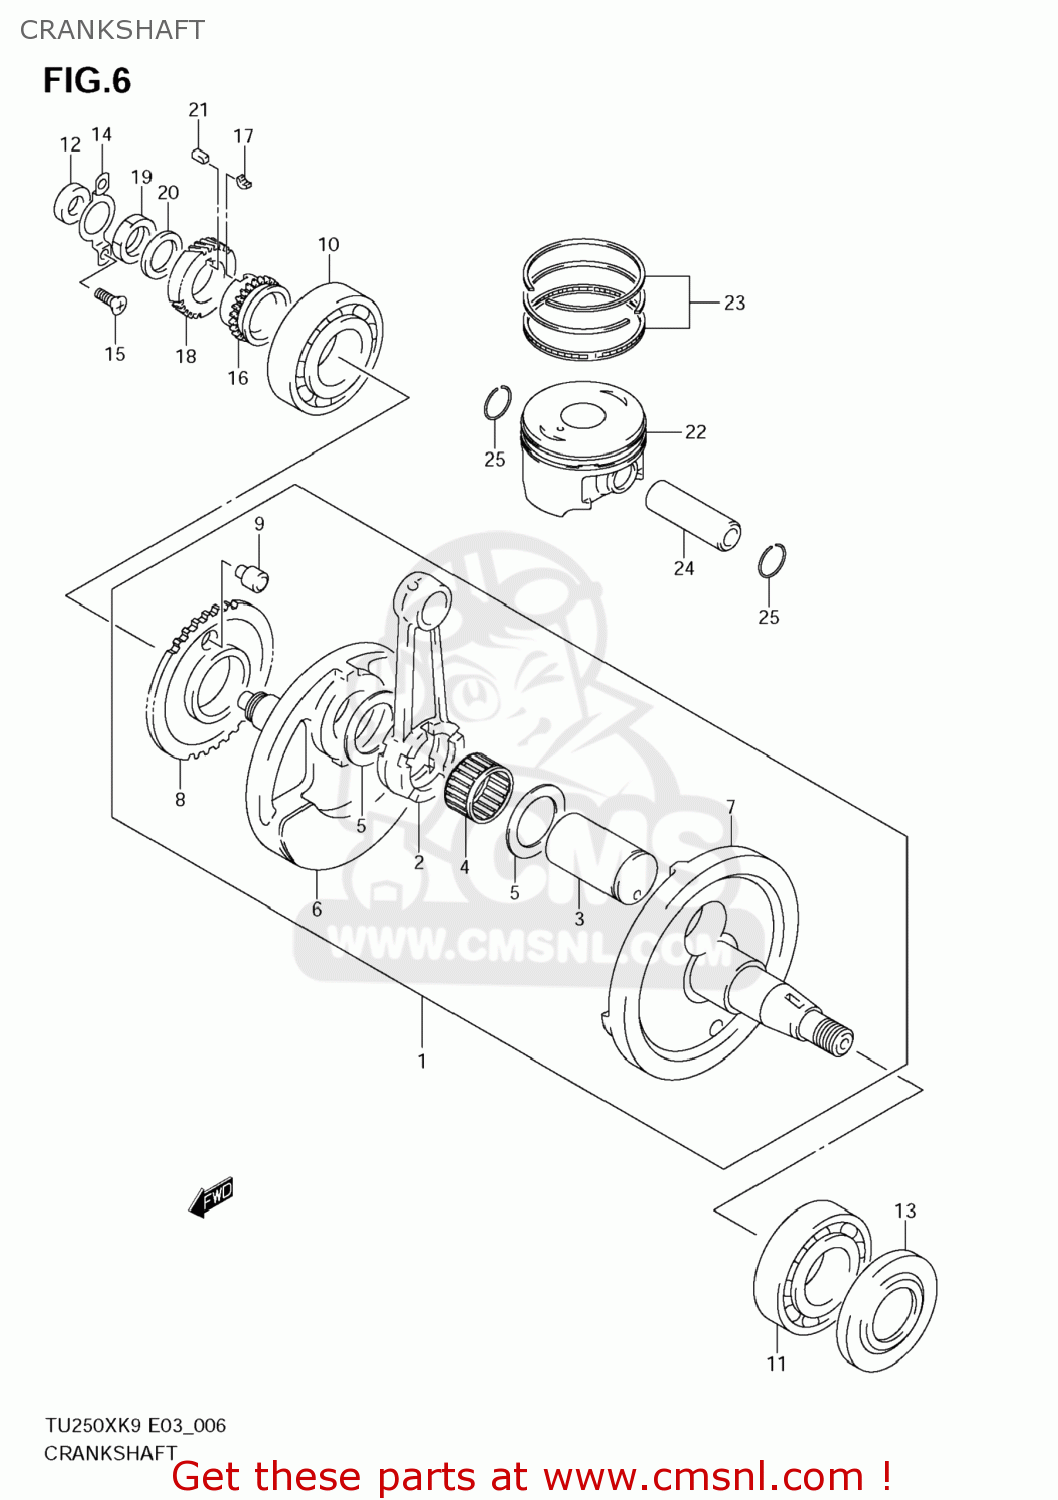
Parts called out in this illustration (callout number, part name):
1	CRANKSHAFT ASSY
2	ROD,CONNECTING
3	PIN,CRANK
4	BEARING(31X39X21)
5	WASHER(31X48.5X1)
6	CRANKSHAFT,R
7	CRANKSHAFT,L
8	GEAR,CRANK BALANCER DRIVE
9	PIN
10	BEARING(30X72X19)
11	BEARING(35X80X21)
12	SEAL,OIL(14X26X6)
13	WASHER,CRANKSHAFT OIL SEALING
14	RETAINER,CRANKSHAFT BEARING,R
15	SCREW
16	SPROCKET,CAM CHAIN DRIVE
17	KEY,SPROCKET
18	GEAR,PRIMARY DRIVE NO.21
19	NUT (20MM)
20	WASHER
21	KEY
22	PISTON
23	RING SET,PISTON
24	PIN,PISTON
25	CIRCLIP
